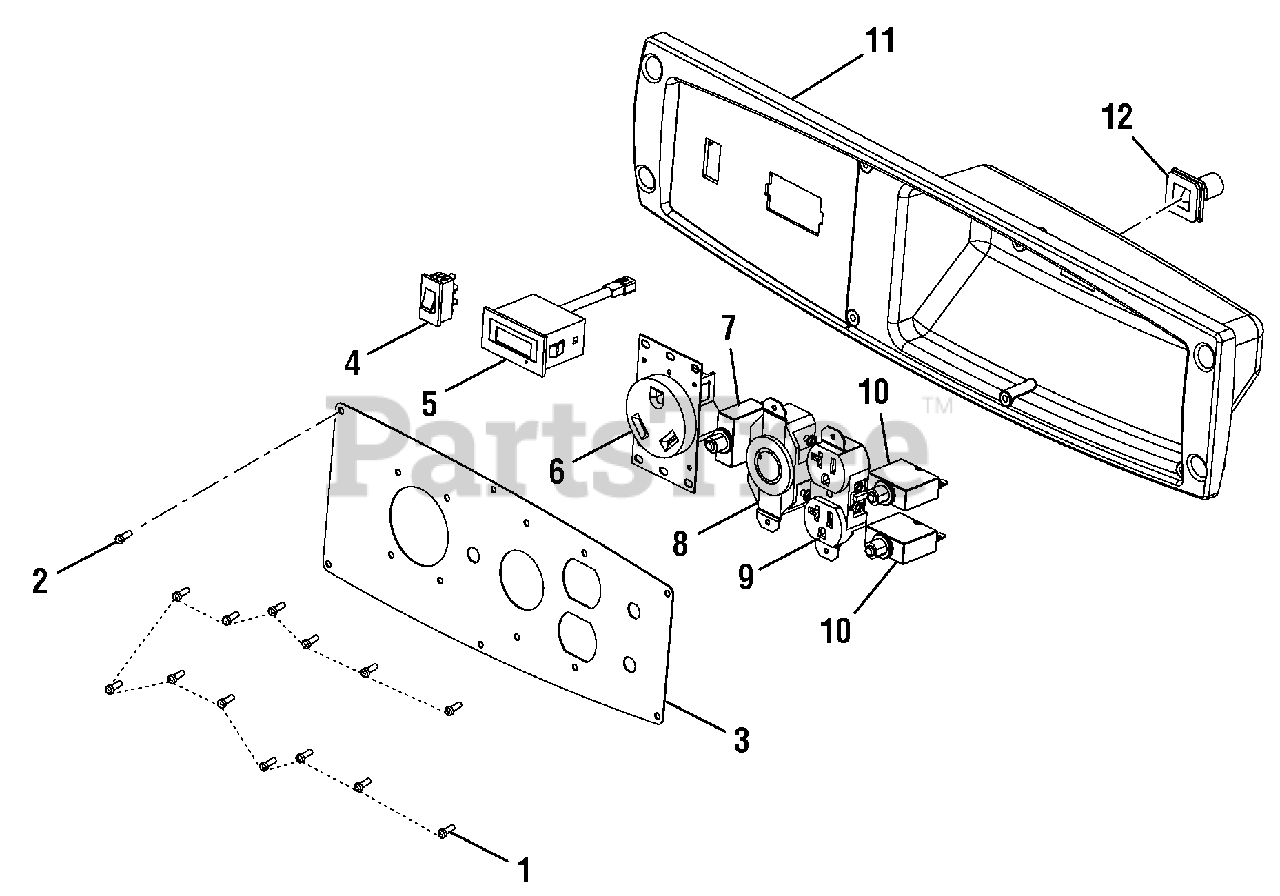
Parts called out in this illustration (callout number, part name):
1	Screw (#6-20 x 9.65 mm)
2	Screw (#6-20 x 20 mm)
3	Electrical Panel Assembly
5	Digital Display
6	120V/30A Recepticle (Twist Lock)
7	30A Circuit Breaker
8	120V/30A Recepticle (RV)
9	120V Duplex Receptacle
10	20A Circuit Breaker
11	Front Panel
12	Rubber Boot
